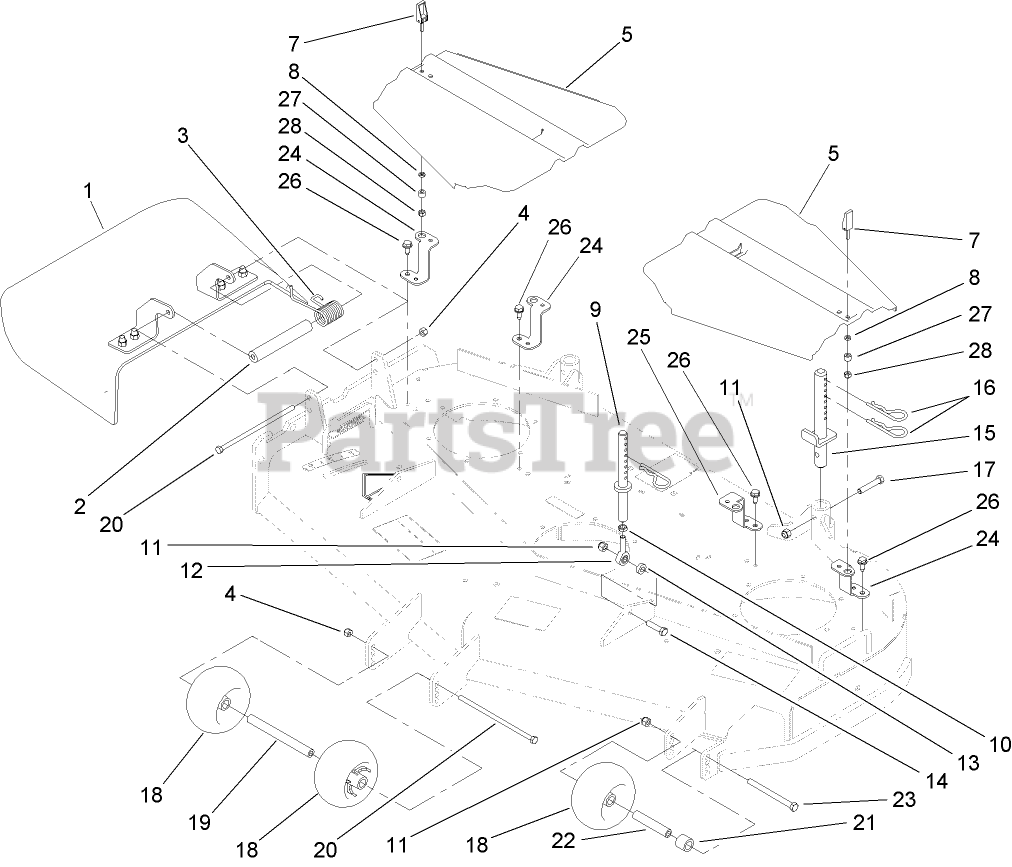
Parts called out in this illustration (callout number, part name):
1	DEFLECTOR ASM
2	SPACER
3	SPRING-TORSION
4	NUT-LOCK, NI
5	COVER-BELT
7	HANDLE-LATCH, SWELL
8	WASHER
9	FRONT PIN ASM
10	NUT-HJ
11	NUT-LOCK, NI
12	BALLJOINT
13	SPACER
14	SCREW-HH
15	REAR PIN ASM
16	PIN-HAIR
17	SCREW-HH
18	ROLLER-SCALP, ANTI
19	SPACER-WHEEL
20	SCREW-HH
21	TUBE-SPACER
22	TUBE-SPANNER
23	SCREW-HH
24	BRACKET-COVER
25	BRACKET-COVER
26	SCREW-HWHTF
27	BUSHING-LATCH, SWELL
28	NUT-LOCK, HH
